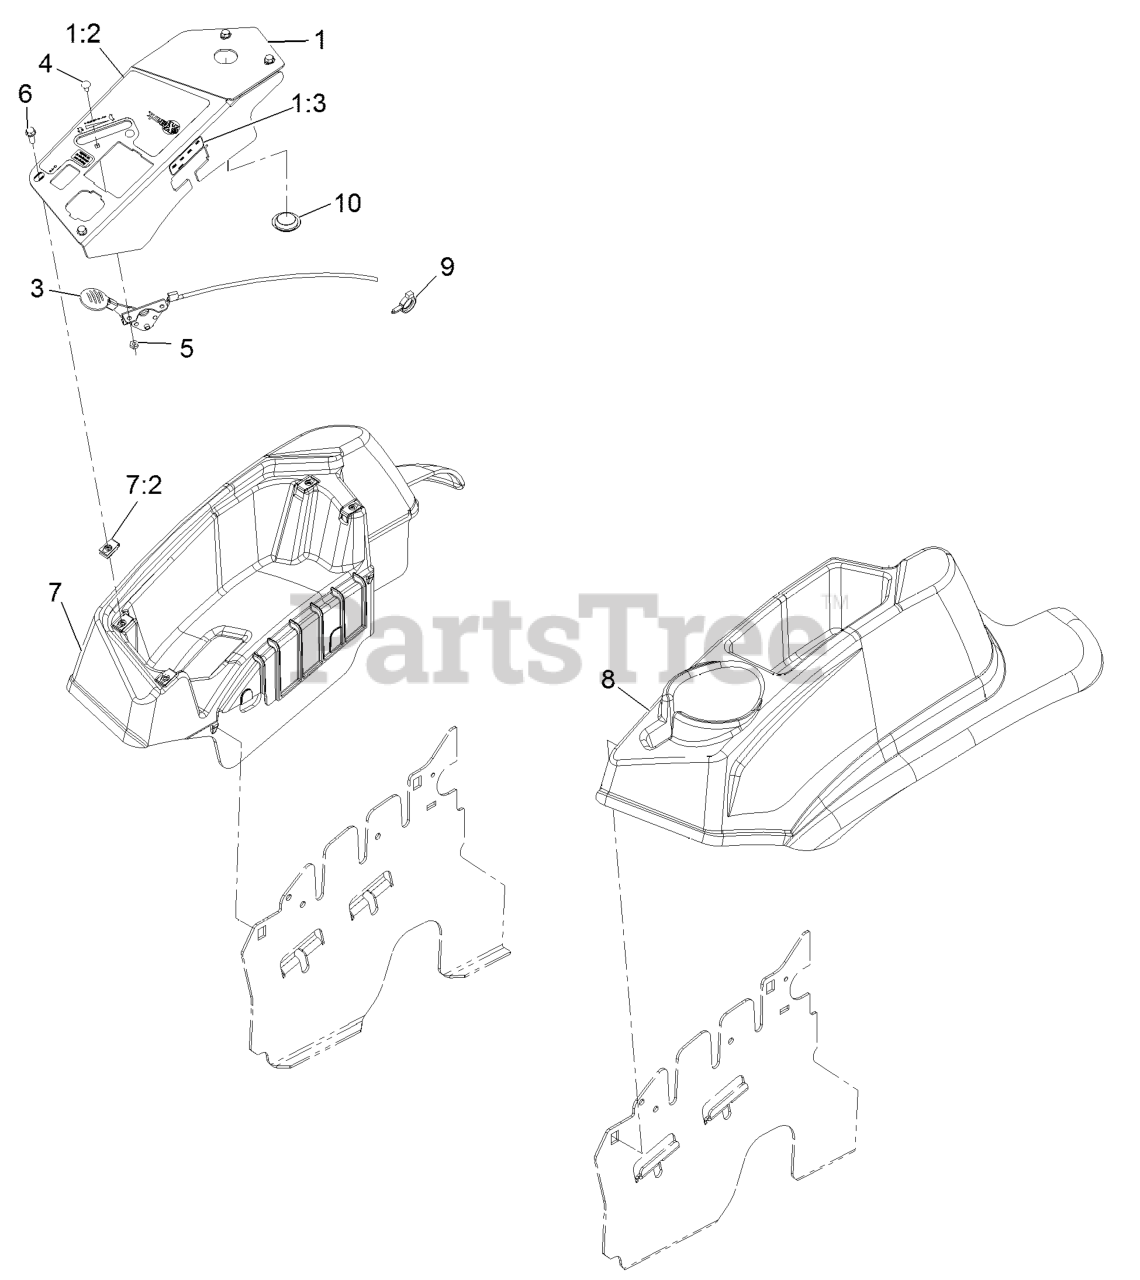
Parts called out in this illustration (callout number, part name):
1	CONTROL PANEL W/DECALS AS
1:2	DECAL,CONTROL PANEL LP
1:3	DECAL-FUSE
3	ASM,THROTTLE CABLE
4	BOLT-CARR
5	NUT-LOCK, NI
6	SCREW-HWH
7	CONSOLE,RH AS ASM
7:2	Nut-Retainer-Panel 1/4-20
8	CONSOLE, LH AS
9	CLAMP-HOSE
10	PLUG-PLASTIC
